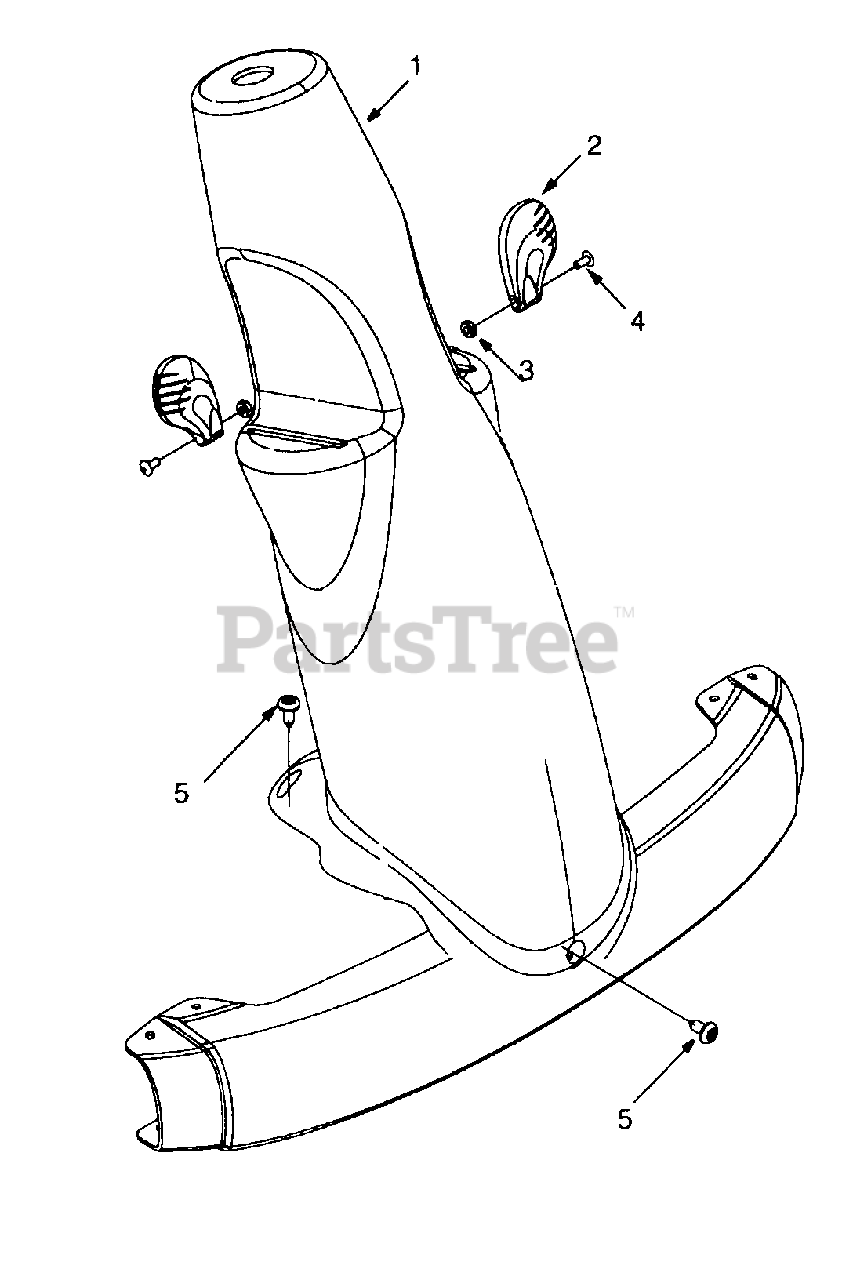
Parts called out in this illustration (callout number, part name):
1	Steering Column: Black
2	Control Knob
3	Hex Nut 8-32
4	Pan Head Machine Screw #8-32
5	Hex Screw TT 1/4-20 x .50"
